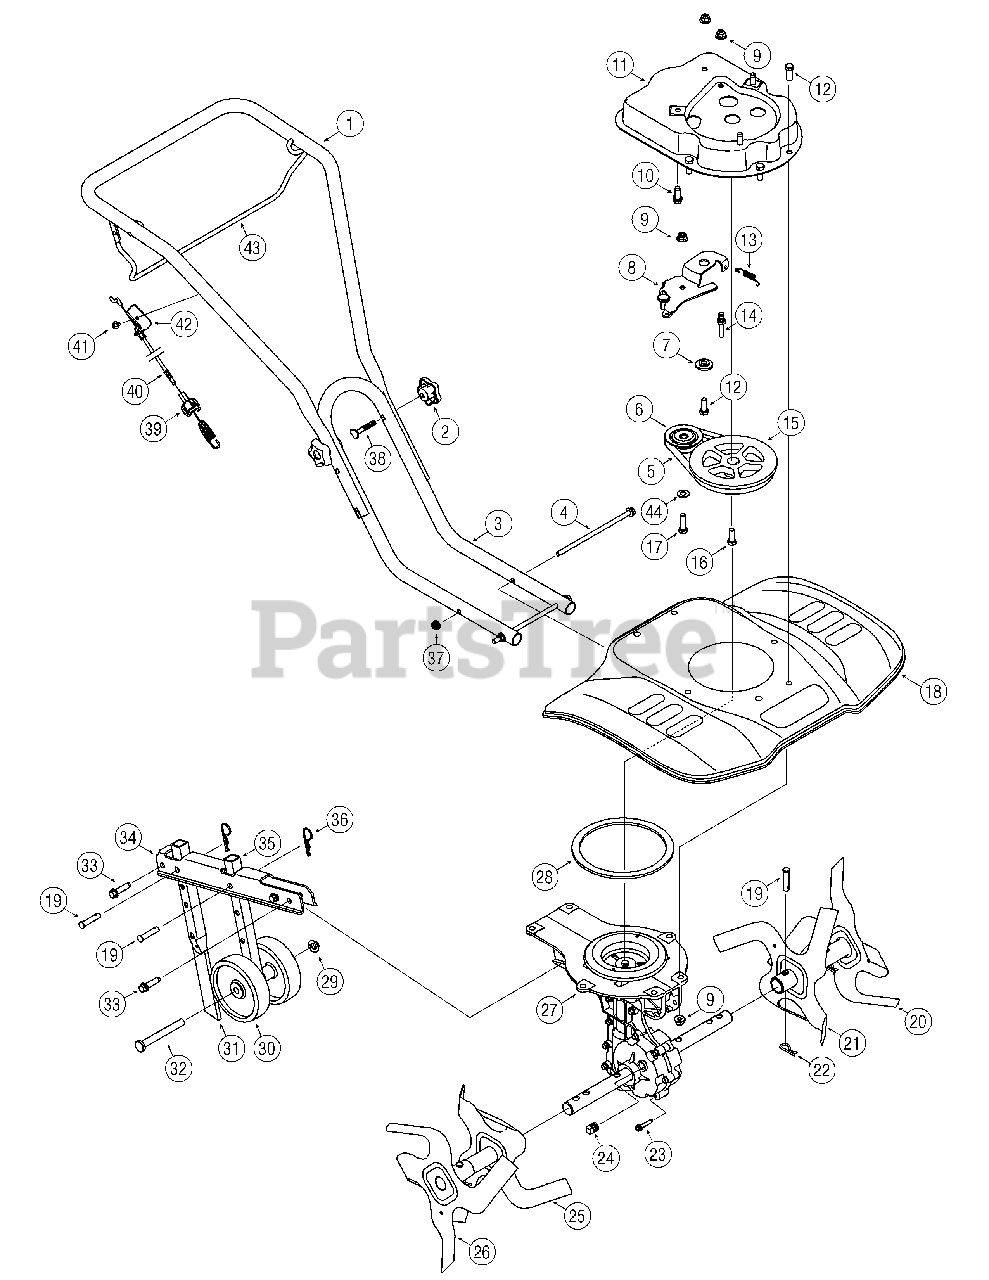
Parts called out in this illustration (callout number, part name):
2	Star Handle Knob
4	Flange Screw 5/16-18 x 7.5
5	Belt
6	Idler Pulley
7	Shoulder Spacer
8	Idler Bracket
9	Flange Lock Nut: 3/8-16
10	TT Screw 3/8-16 x 1.00
12	HH Cap Screw 3/8-16 x 1.00
13	Extension Spring
14	Stud 33 x 1.5 x 3/8-16
15	Flywheel Pulley
16	HH Cap Screw 3/8-24 x 1.00
17	HH Cap Screw 3/8-16 x 1.50
19	Clevis Pin
22	Internal Cotter Pin
23	TT Screw 1/4-20 x 1.25
24	Pipe Plug 3/8 NPT
27	Case Assembly
28	Gasket
29	Push Cap
30	Wheel 5 x 1.38
32	Axle Shaft
33	TT Screw 3/8-16 x 1.50
36	Internal Cotter Pin
37	Flange Lock Nut: 5/16-18
38	Carriage Bolt
39	Clutch Cable Fitting
40	Clutch Cable
41	TT Screw 1/4-20 x .50
44	Flat Washer .406 x .875 x .059
